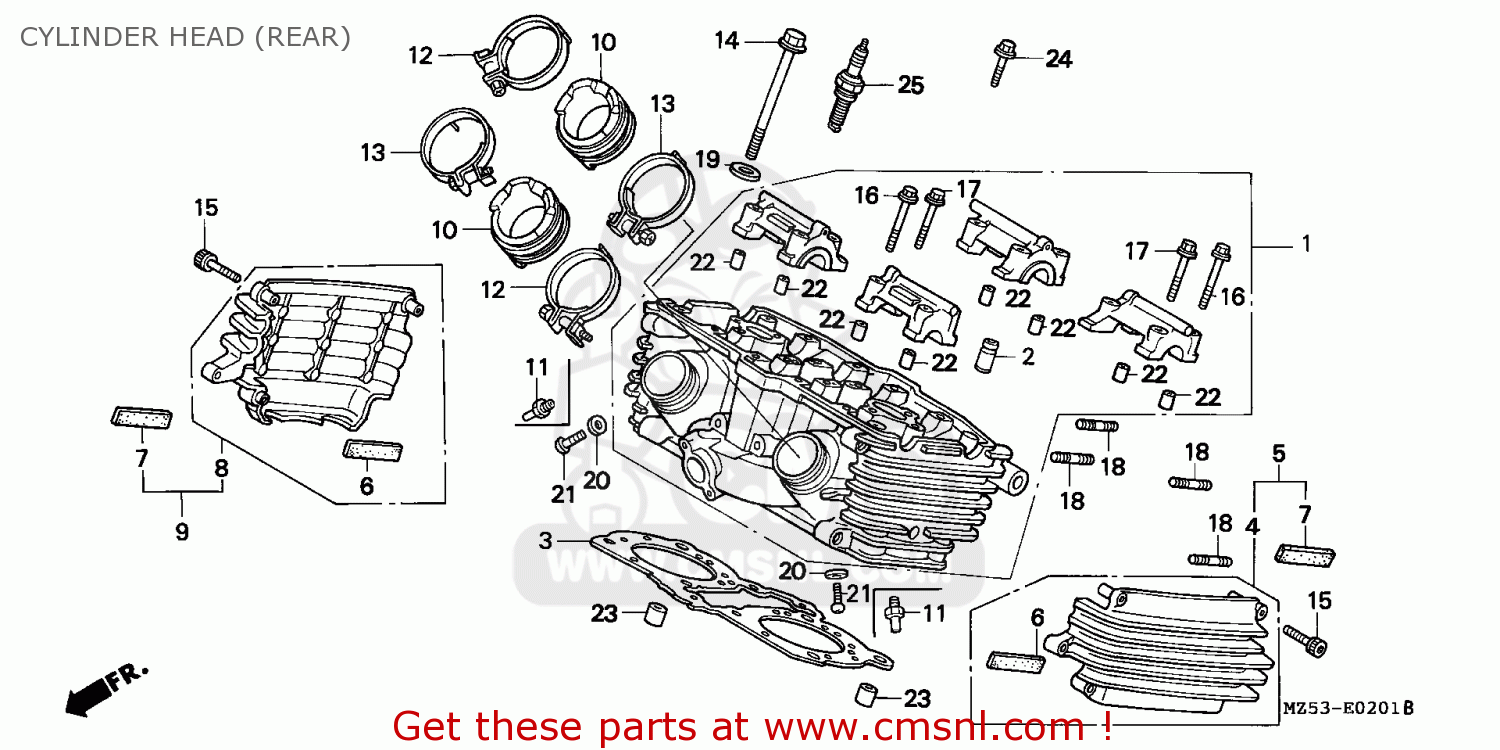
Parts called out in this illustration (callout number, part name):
1	HEAD ASSY,RR
2	GUIDE,VALVE
3	GASKET,CYLN HEAD (NAS)
5	FIN COMP A,CYLN H
6	RUBBER,SEAT
7	RUBBER A,SEAT
9	FIN COMP B,CYLN H
10	INSULATOR,CARB
12	BAND A,INSULATOR
13	BAND B,INSULATOR
14	BOLT,FLANGE,9X93
15	SOCKET BOLT,6X28(
16	BOLT,FLG.,6X45.5
17	BOLT,FLG.,6X39.5
18	BOLT,STUD,6X22(CT
19	WASHER,9MM
20	WASHER 5MM
21	SCREW,CROSS 5X8
23	DOWEL,PIN,12X20
24	BOLT,FLANGE 6X30
25	PLUG,SPARK(CR8EH9
